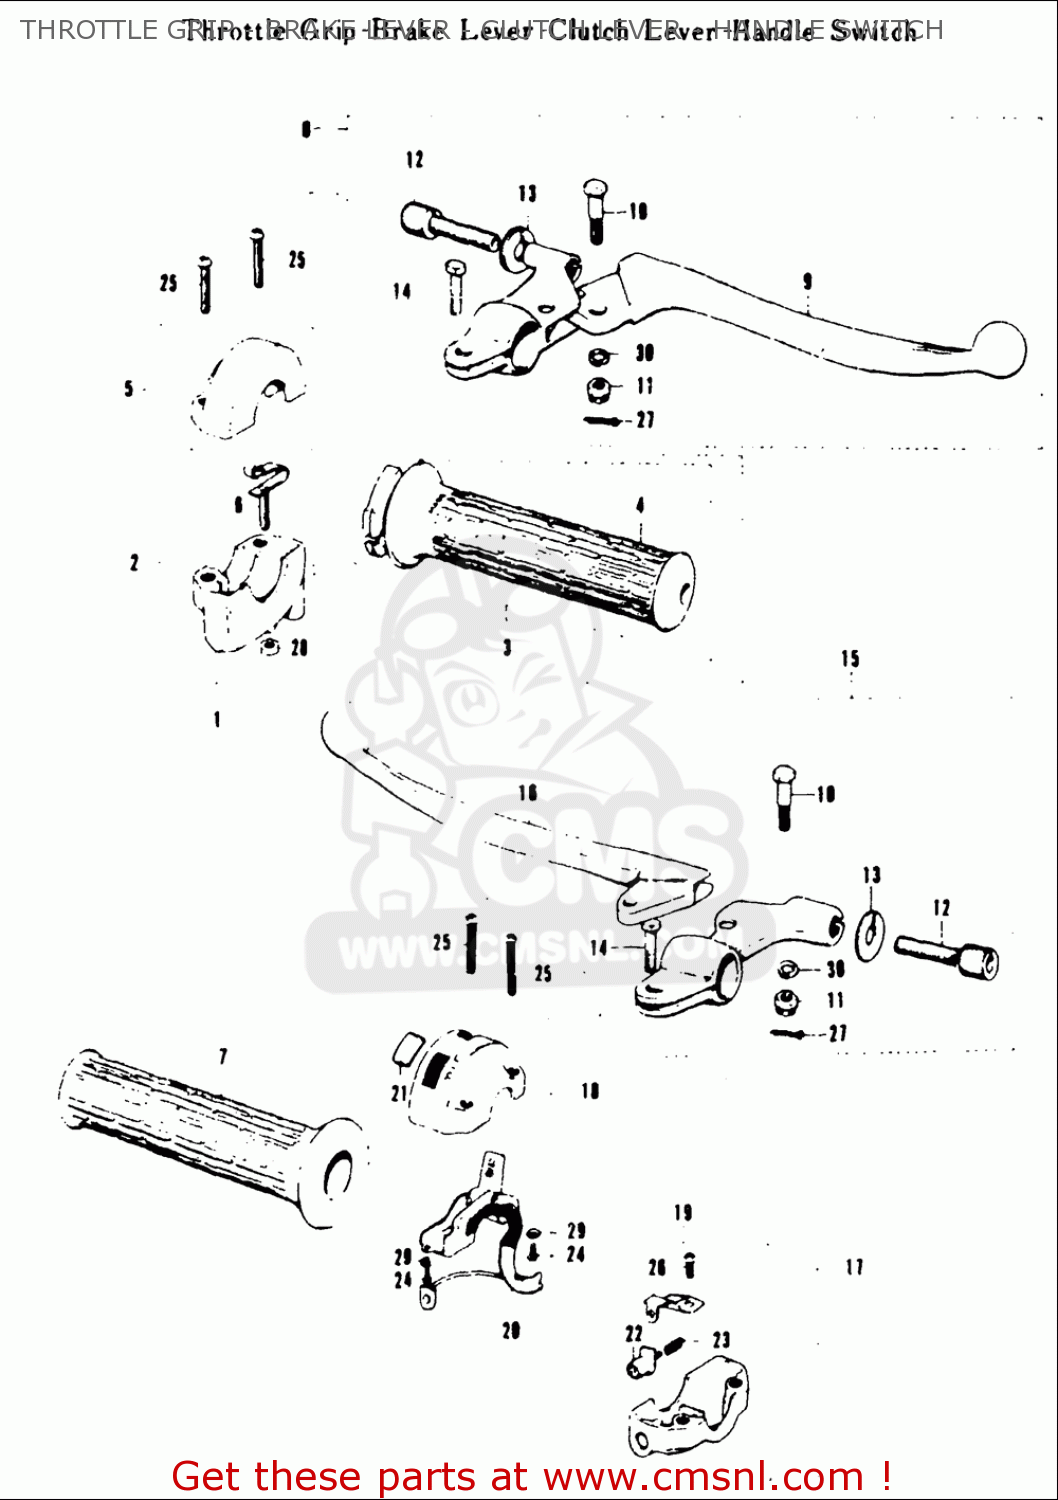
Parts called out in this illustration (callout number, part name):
6	ADJUSTER, THROTTLE
7	GRIP
10	BOLT,LEVER PIVOT
11	NUT,LEVER FITTNG
12	ADJUSTER,CABLE
13	NUT,CABLE ADJUSTER
14	BOLT
22	BUTTON, HORN
25	SCREW
26	SCREW
27	PIN 16X20
28	NUT
29	WASHER,LOCK
30	WASHER,LOCK
